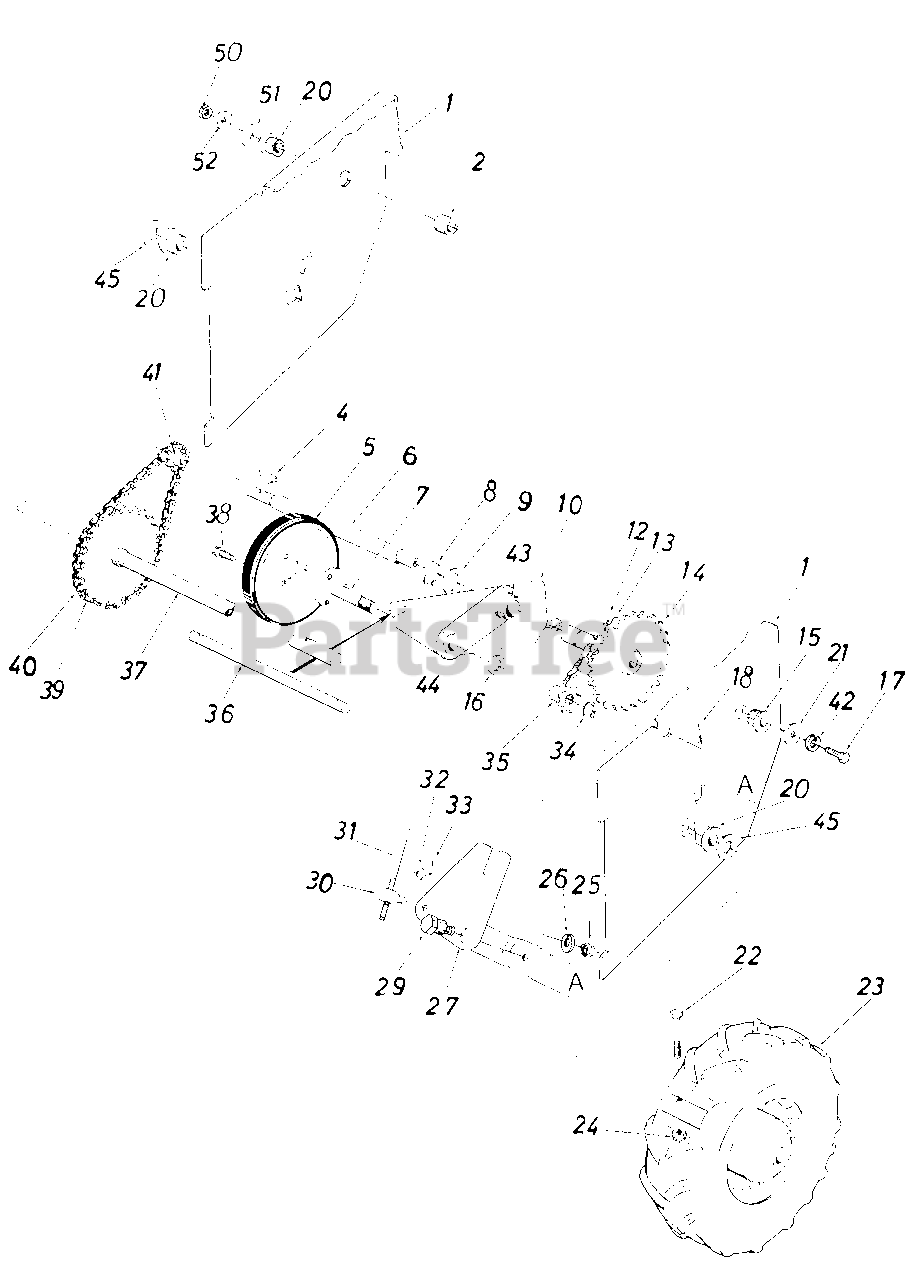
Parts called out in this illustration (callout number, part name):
1	Frame Ass'y.
2	Spacer .50" I.D. x .75" O.D. x.78" Lg.
4	#4 Hi-Pro Key 3/32 x 5/8" Dia.
5	Friction Wheel Ass'y.
6	Hex Shaft
7	Friction Wheel Mounting Plate Ass'y.
8	Snap Ring 1.00" Dia. Shaft
9	Fl-Wash. 1.00" x 1.63" O.D. x .03
10	Sliding Bracket Ass'y.
12	#41 Chain 1/2" Pitch x 35 Links
13	Master Link for #41 Chain
14	32 Teeth Sprocket Ass'y.
15	Hex Flange Brg. .630" I.D.
16	Fl-Wash. .62" I.D. x 1.00" O.D. x .06
17	Hex Lock Bolt 5/16-18 x .62" Lg. *
18	Cotter Pin 3/32" Dia. x .75" Lg. *
20	Flange Brg. w/Flats .755" I.D.
21	Fl-Wash. .34" I.D. x 1.12" O.D. x .125
22	Hex Bolt 5/16-24 x 1.50" Lg.
23	Wheel Ass'y. Comp.-L.H. 12.5 x 3.5
24	Hex Ins. Jam L-Nut 5/16-24 Thd.
25	Hex Jam Nut 3/8-16 Thd.*
26	L-Wash. 3/8" I.D.*
27	Shifting Linkage Bracket
29	Shld. Bolt .625" Dia. x .170" Lg.
30	Adjustment Ferrule
31	Shifting Rod 5/16" Dia. x 32.50" Lg.
32	Fl-Wash. .34" I.D. x .64" O.D x .06
33	Cotter Pin 3/32" Dia. x .75" Lg.*
34	Snap Ring .562" Dia. Shaft
35	Sprocket 7 Teeth x .50" Pitch
36	Shaft .50" Dia. x 9.50" Lg.
37	32 Teeth Wheel Axle Ass'y.
38	Hex Wash. Hd. Self-Tap Scr. 5/16-24 x .50" Lg.
39	#420 Chain 1/2" Pitch x 39 Links
40	Master Link for #420 Chain
41	8 Teeth Center Sprocket
42	L-Wash. 5/16" I.D.
43	Plastic Bearing
44	Bronze Bearing
45	Fl-Wash. .76" I.D. x 1.49 O.D.
50	Hex Ins. L-Nut 1/2-20 Thd.
51	Fl-Wash. .53 I.D. x 1.25 O.D. x.10
52	Bell-Wash. .50 I.D. x 1.0 O.D. x .075
